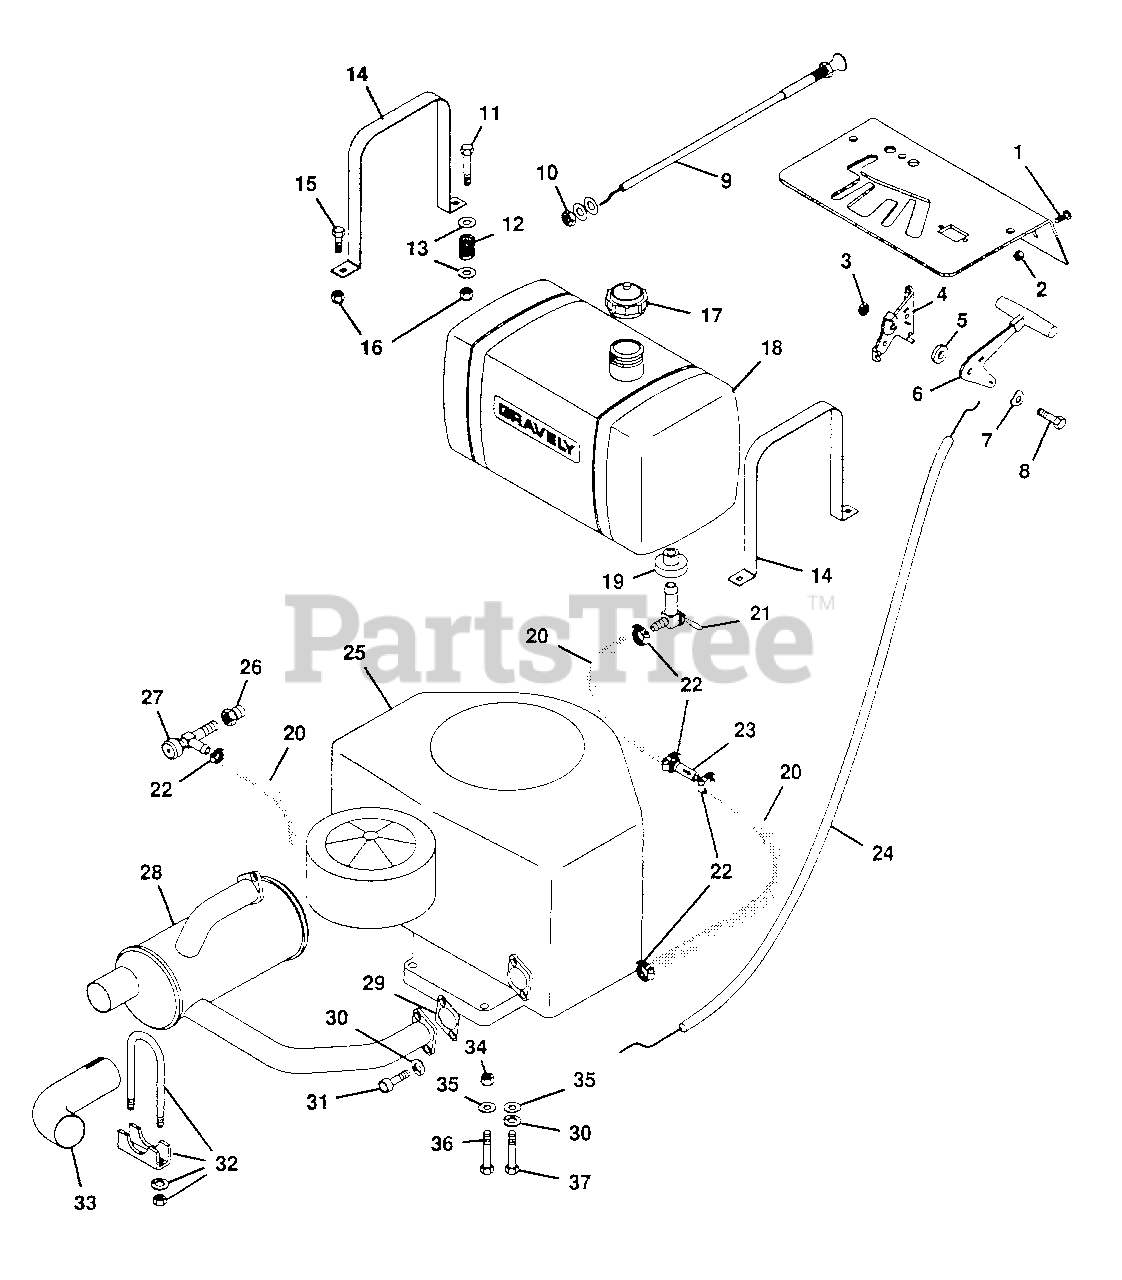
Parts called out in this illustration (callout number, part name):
1	SCREW, MACH. 10-32X.50 PHD
2	NUT, LOCK 10-32
3	NUT, LOCK 1/4-28
4	BRACKET, MOUNTING L.H.
5	WASHER, FRICTION
6	ASSEMBLY, KNOB AND LEVER
7	WASHER, SPRING
8	BOLT, HEX 1/4-28X.75
9	CONTROL, CHOKE
10	NUT, JAM 3/8-24 HEX
11	BOLT, HEX 1/4-20X1.75
12	SPRING, COMP. 1X.78X338 LB/IN
13	WASHER, FLAT .281X.625X.065
14	STRAP, FUEL TANK
15	BOLT, HEX 1/4-20X.625
16	NUT, LOCK 1/4-20
17	CAP, FUEL TANK
18	TANK, FUEL
19	BUSH., FLG. .375X1.06X.625 RB.
20	LINE, FUEL
21	VALVE, BALL SHUT-OFF
22	CLAMP, HOSE
24	ASSEMBLY, THROTTLE CONDUIT
25	ENGINE, 18 HP KOHLER
26	ADAPTOR, OIL DRAIN
27	COCK, OIL DRAIN
28	MUFFLER
29	GASKET, EXHAUST
30	WASHER, LOCK 5/16 REG.
31	SCREW, CAP 5/16-18X.75 SHD
32	CLAMP, U 1.75
33	DEFLECTOR
34	NUT, LOCK 5/16-18
35	WASHER, FLAT .344X.688X.065
36	BOLT HEX 5/16-18X1.75
